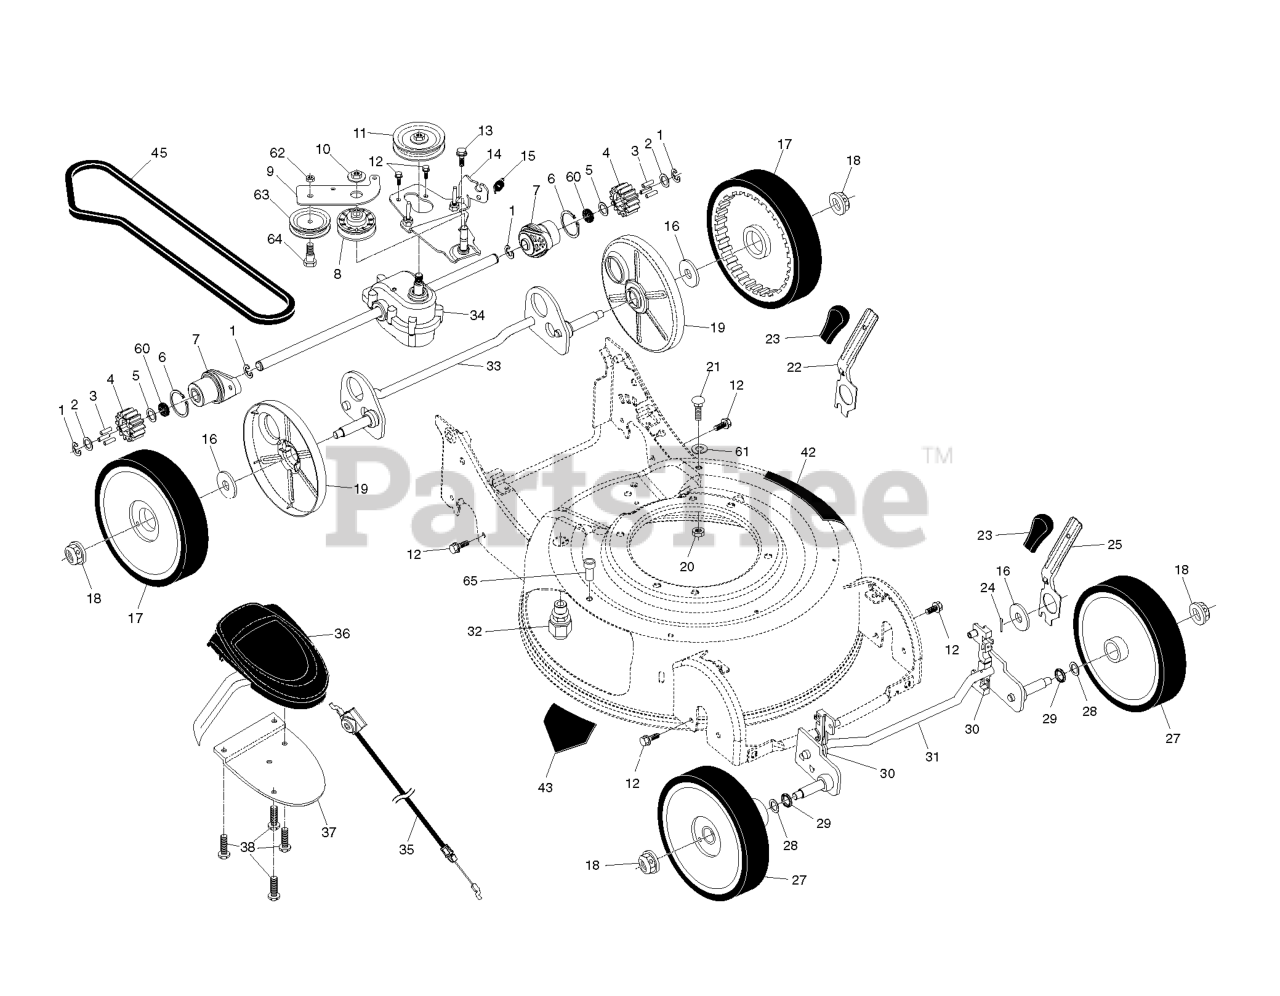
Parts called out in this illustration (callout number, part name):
1	E-RING 7/16 RE
2	THRUST WASHER
3	PAWL.DRIVE.ETCHED
4	PINION.DRIVE.WALK
6	RETAINING RING (2 2)(3 2)
8	PULLEY.IDLER.V-BELT
9	ARM.IDLER.BZP
10	NUT.HEX.FLANGE.3/8-16.LOCKNUT
11	PULLEY.1.PIECE
13	SCREW 14-20 X 5/8
15	SPRING.RETURN
16	WASHER FLUT
17	WHEEL.8X1.75.H3SPK.RAD3.GY.BU3
18	NUT.HEX.FLANGE.3/8-16.LO(3 2)
19	COVER.DUST.WHEEL
20	NUT, HEX
21	BOLT.CARRIAGE.1/4-20 X 7/8
24	SPRING RETAINER
27	WHEEL & TIRES ASSY, FRONT
28	WASHER.FLAT.1/2
29	O-RING..070X.487.NEOPRENE
30	BUSHING.FRONT.TORQUE.S
37	BRACKET.DRIVE.CONTROL.MOUNT.BL
38	SCREW, PHILLIPS HEAD 10 X 5/8
43	DECAL.INTERNATIONL.CUTFINGER
61	LOCKWASHER
62	NUT.CENTERLOCK.5/16-
63	IDLER PULLEY
64	SHOULDER BOLT
